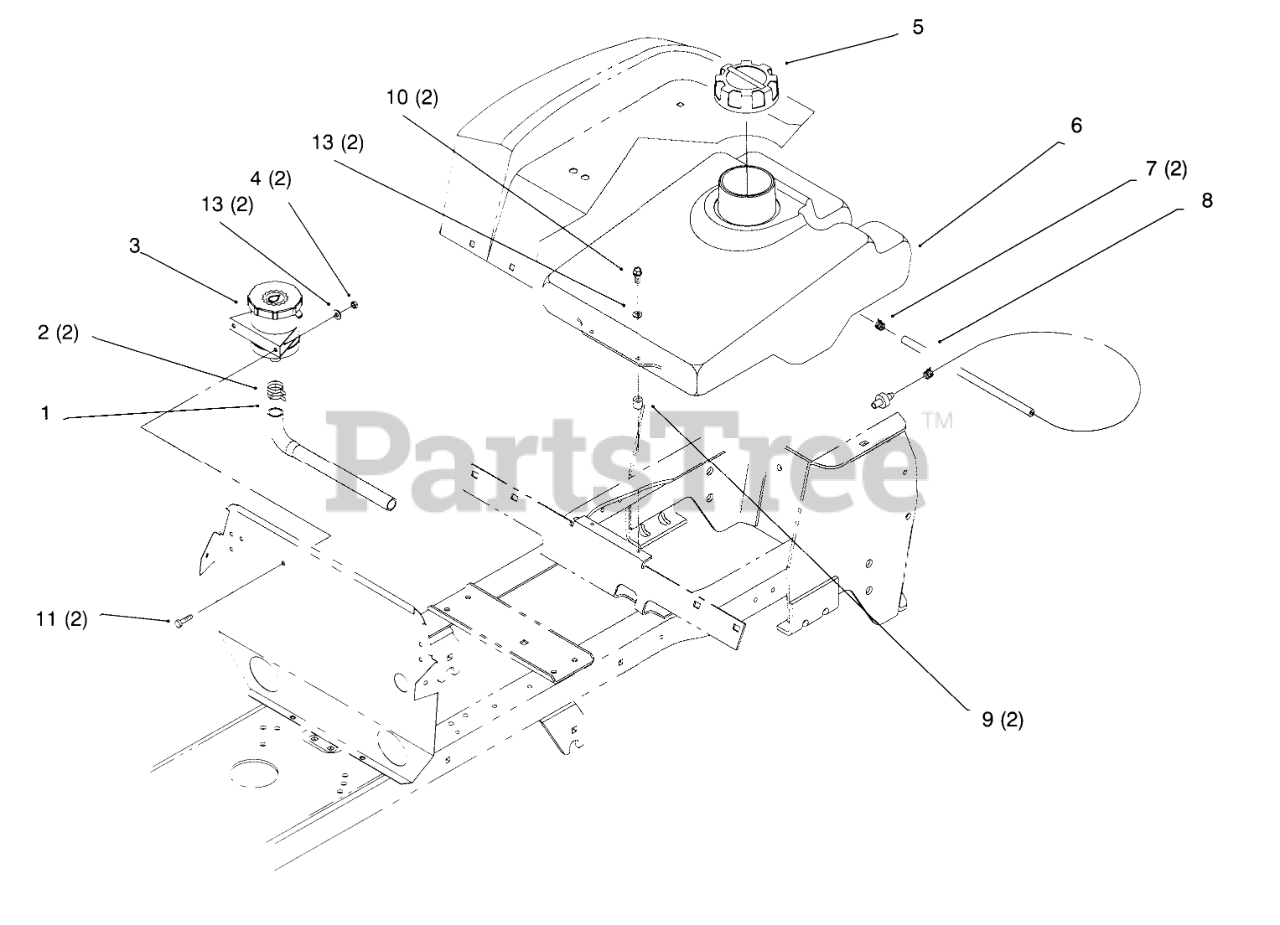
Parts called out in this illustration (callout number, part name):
1	HOSE - HYDRO
2	CLAMP-HOSE
3	ASS'Y-RESERVOIR
4	NUT-LOCK, NI
5	GAS CAP ASM
6	Tank-Gas
7	CLAMP-HOSE
8	HOSE - FUEL LINE TWIN
9	SPACER - FUEL TANK
10	SCREW-HH
11	SCREW-HH
13	WASHER-FLAT
